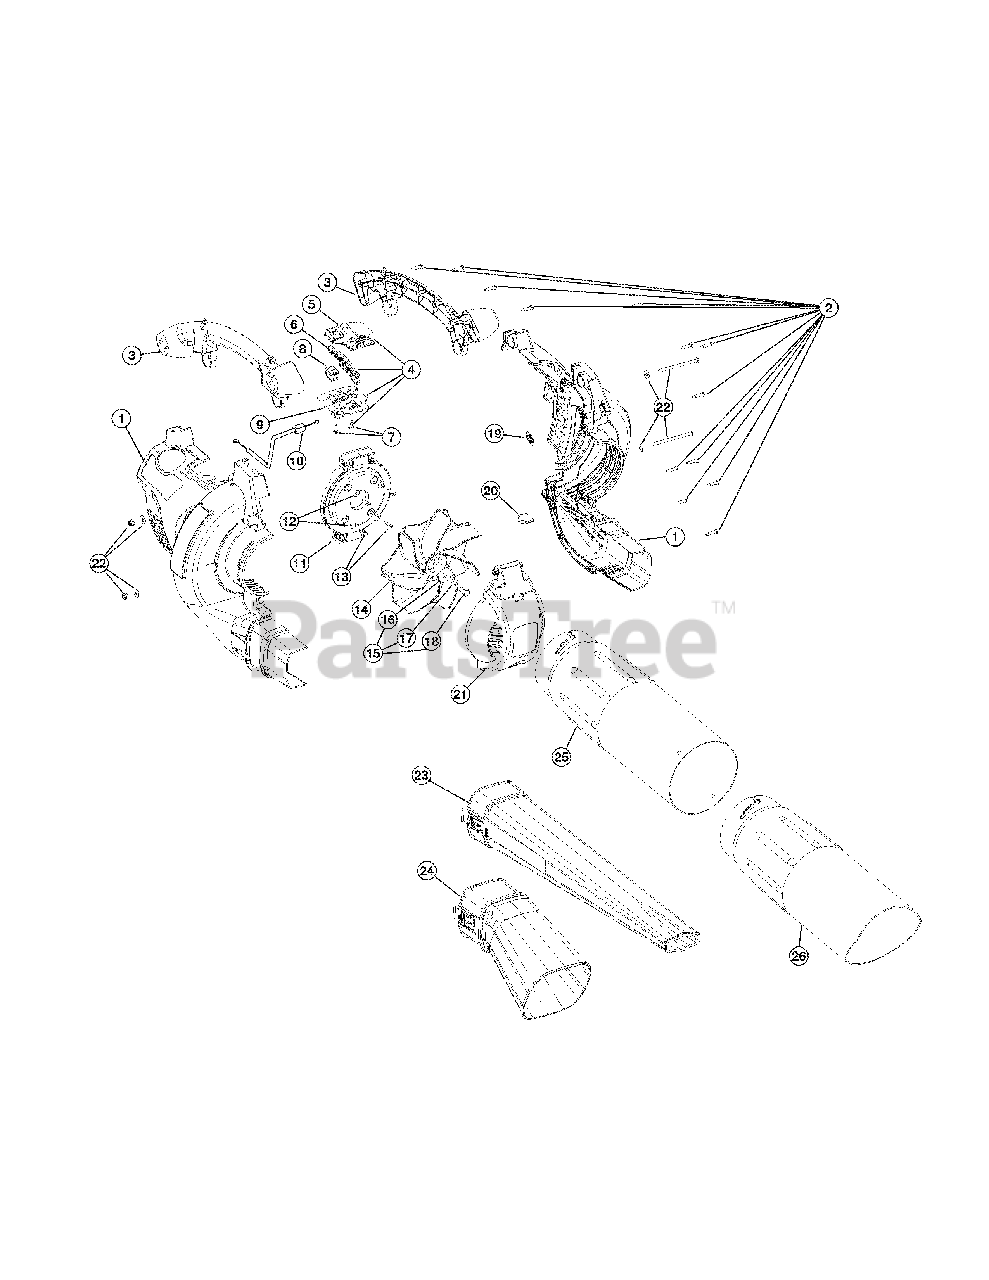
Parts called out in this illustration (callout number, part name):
1	Engine Cover Assm (includes 2)
3	Handle Assm (includes 2)
4	Throttle control Assm (includes 5-9)
5	Upper Throttle Control Plate
6	Throttle Control Lever
8	Rocker Switch Assm
9	Lower Throttle Control Plate
10	Throttle Cable
11	Engine Mount Plate (includes 12 & 13)
13	Screw
14	Impeller Blade
15	Impeller Hardware (includes 16-18)
16	Washer
17	Lock Washer
19	Vacuum Door Spring
20	Vacuum Door Lock
21	Vacuum Door
22	Mounting Plate Hardware
23	Blower Tube
24	Vacuum Bag Adaptor
25	Upper Vacuum Tube
26	Lower Vacuum Tube
